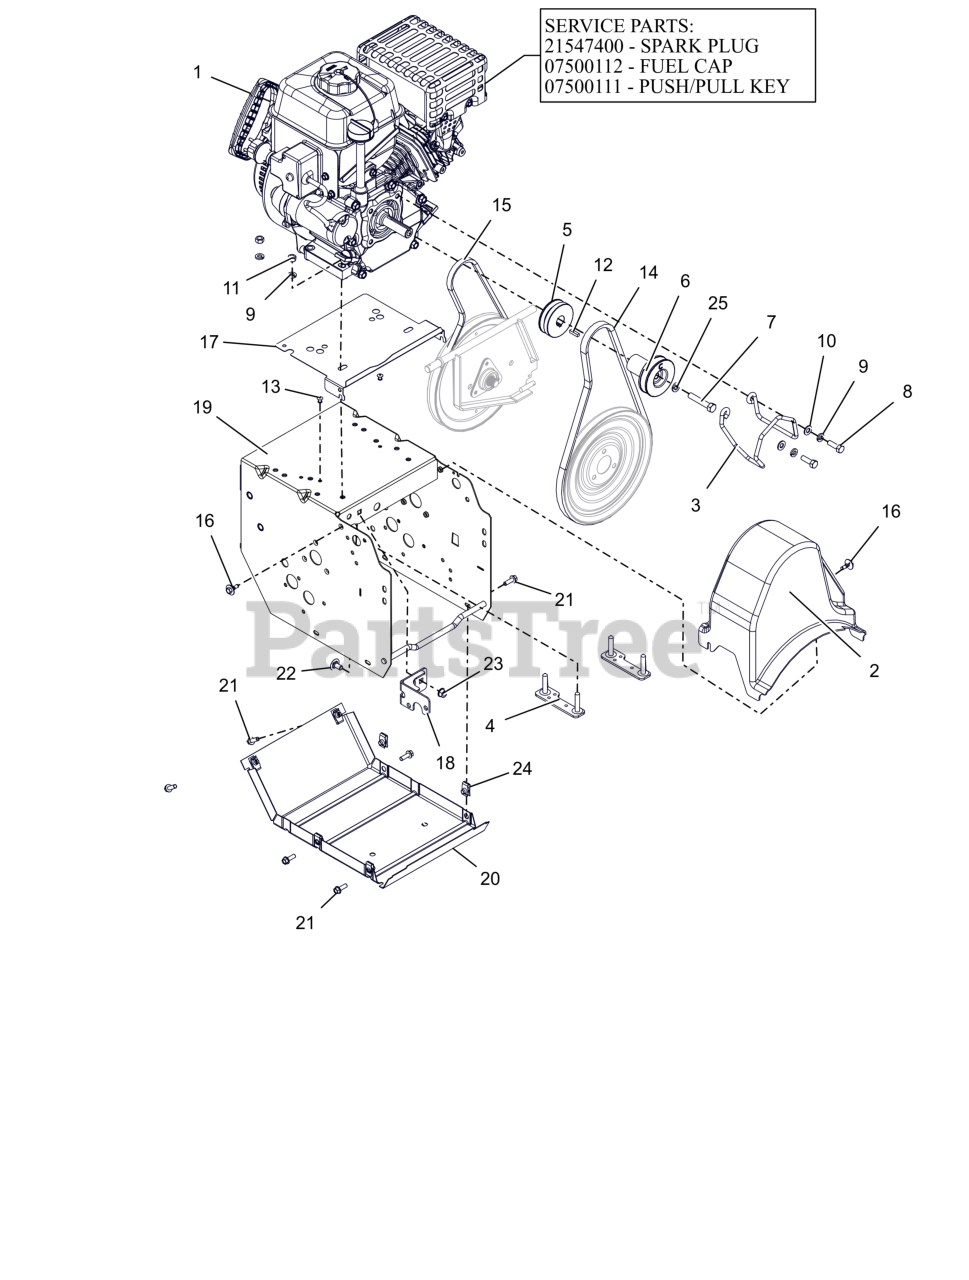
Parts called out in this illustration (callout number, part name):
1	ENGINE, ARIENS AX208 240V/60W
1	PLUG, SPARK
1	CAP, FUEL TANK BLACK
1	KEY, PUSH/PULL LCT (2/PACKAGE)
2	COVER, COMPACT BELT
3	FINGER, BELT
4	STRAP, ENGINE BOLT-WELDMENT
5	SHEAVE, TRACTION-COMPACT TRACK
6	SHEAVE, ATTACHMENT SINGLE GRV
7	BLT, HEX .38-24X2.00 G5 ZCC
8	BLT, HEX 0.3125-24X1 G5 ZCC
9	WSHR, LK-HVY .312X.097 ZCC
10	WSHR,FLT .344X.688X.065 ZCC
11	NUT, HEX .312-18 ZCC
12	KEY-SQ .188X.75X.188
13	RVT, POP .1875 ZCC
14	V-BELT, HA-RAW EDGE
15	V-BELT, 3L-WRAPPED
16	SCR-TAP .25-20X.5 CAPTIVE
17	BAFFLE, COMPACT
18	WELDMENT, FRAME BRACKET
19	FRAME, MAIN-WELDMENT
20	COVER, BOTTOM
21	BLT, HWH .25-20X.75 G5 ZCC
22	BLT, RHSSN .31-18X.625 G5 ZCC
23	NUT-LK-TOP-FLG .312-18 GF ZCC
24	NUT-RTNR .25-20X.56
25	WSHR,LK-REG .375X.094 ZCC
